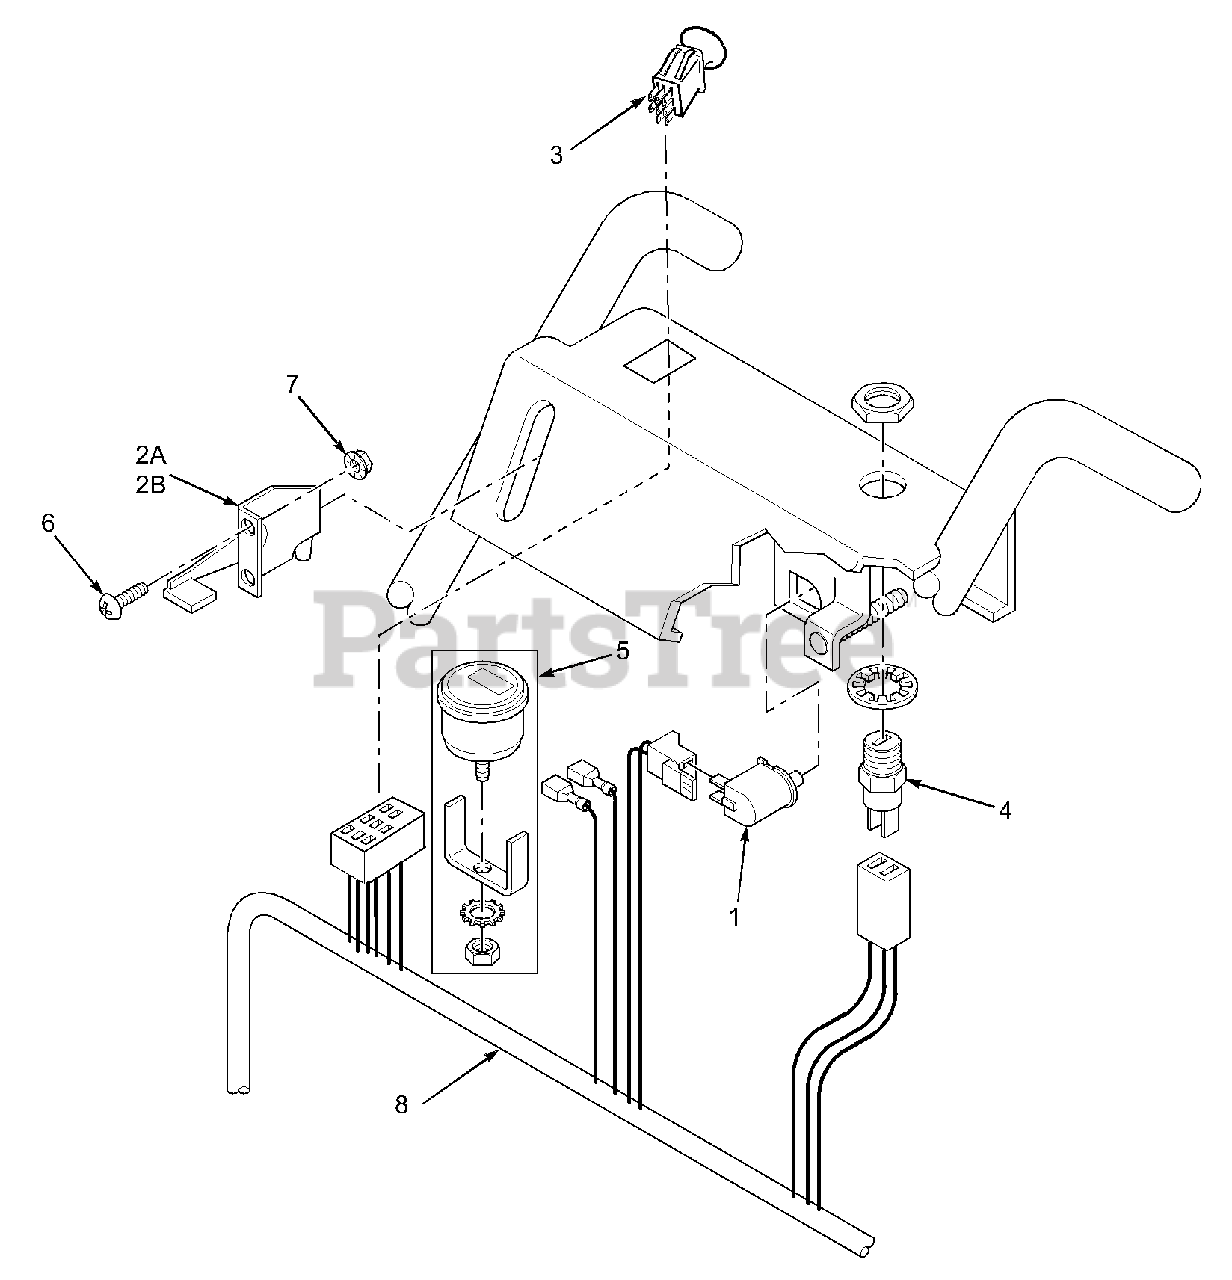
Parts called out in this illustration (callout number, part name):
1	Switch, Neutral Interlock
2A	Throttle Control
2B	Throttle Control
3	Engagement Switch, Electric Clutch
4	Key Switch
5	Hour Meter
6	Screw, #10-32 x .50 Phillips Washer Head
7	Nut, #10-32 Serrated Flange Hex Head
8	Handle Wire Harness, Manual Start
